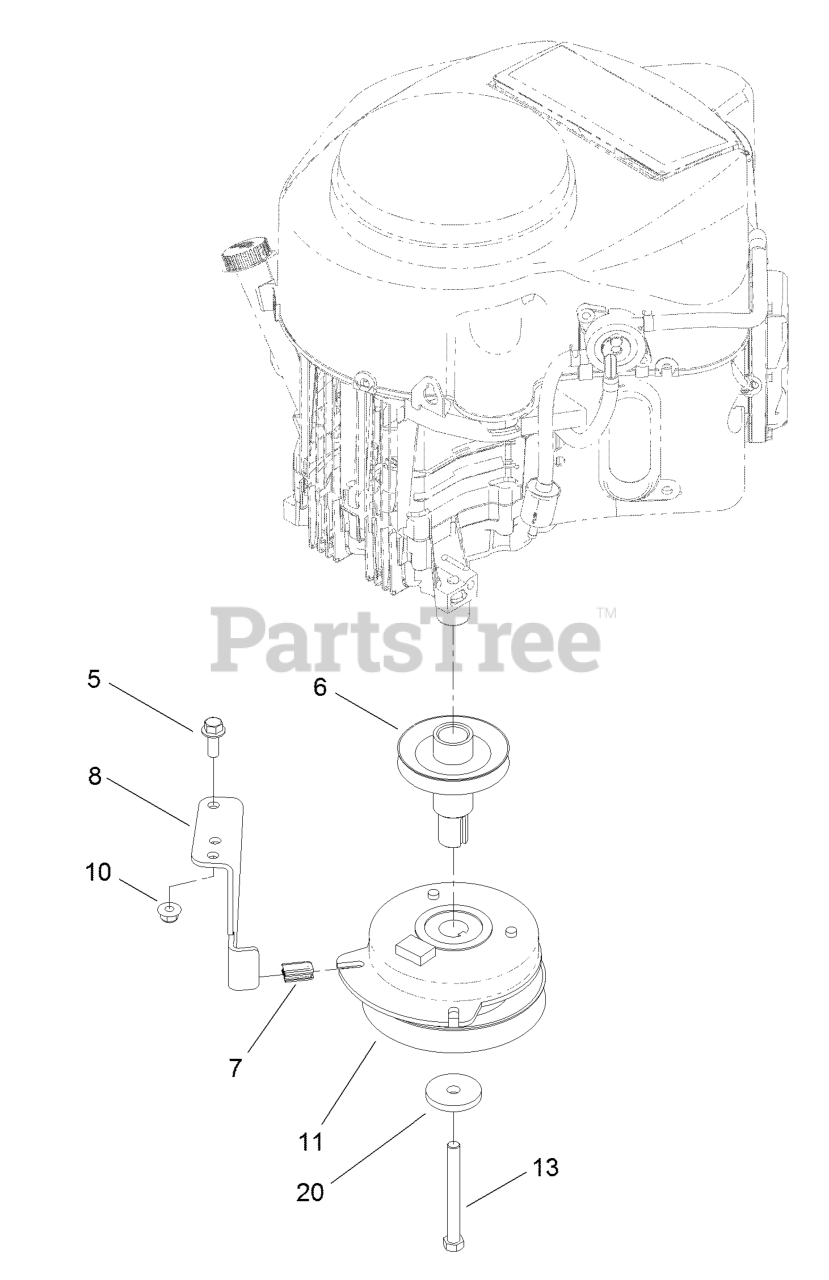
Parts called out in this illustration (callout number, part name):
5	SCREW-HHF 3/8-16 X 1
6	PULLEY-ENGINE
7	ISOLATOR-CLUTCH
8	STOP-CLUTCH
10	NUT-HF, NI
11	CLUTCH-PTO
13	SCREW-HH
20	WASHER-CLUTCH
